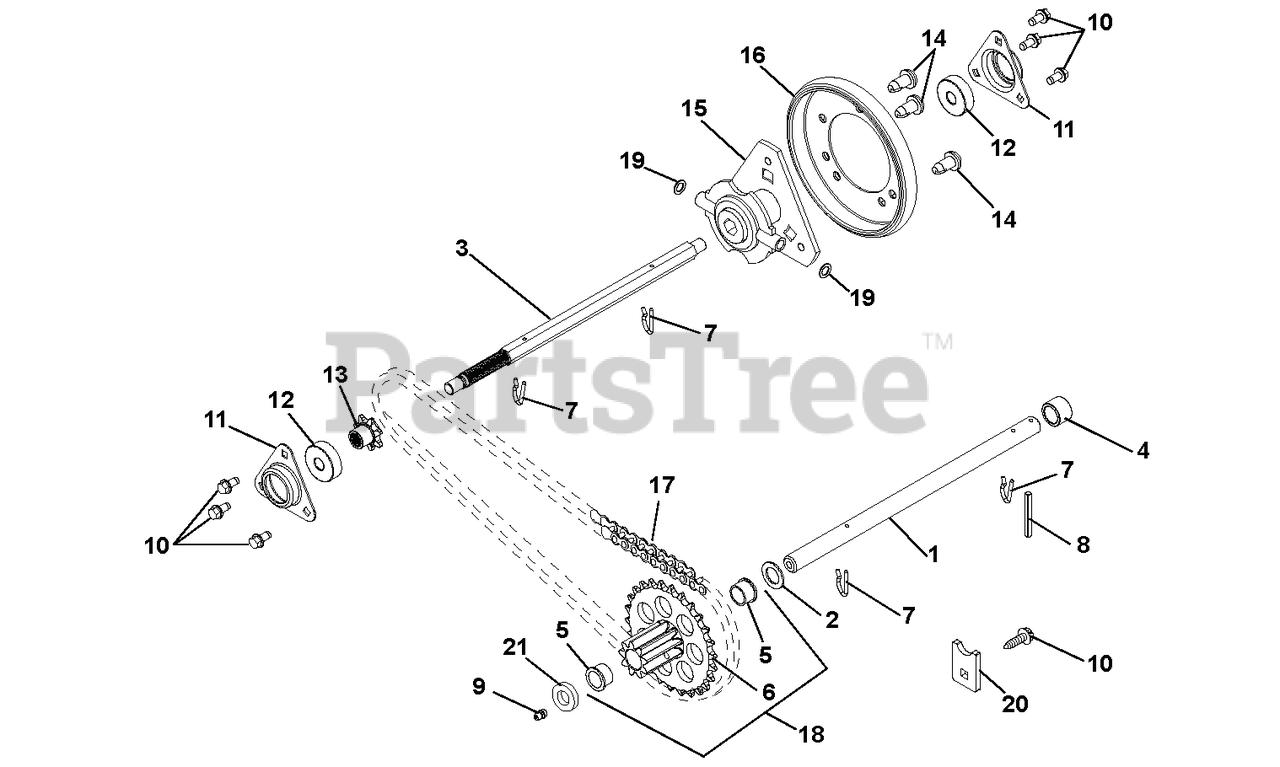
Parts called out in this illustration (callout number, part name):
1	SHAFT, PINION - HARDENED
2	WSHR-FL-STL .630X1.005X.062 YZ
3	SHAFT, HEX-W/SPLINE TRACK
4	SPACER, .635X.880X.611
5	BSHG-FLG .625X.750X.500X.875
6	PINION & SPROCKET
7	PIN, SPRING CLIP
8	@PIN-GRV .125X1.00 TP E ALLOY
9	ZERK,FITTING .25X.125 DRIVE IN
10	SCR-TAP .25-20X.50 HWH TR YWZ
11	FLANGE, BEARING
12	BRG-BALL .437X1.375X.437
13	SPROCKET, PINION 7T W/SPLINE
14	SCR-TAP SERRDHDTX .31-18X.50BP
15	CARRIER, DRIVE DISK
16	FRICTION, DISC
17	CHAIN - #41, 32 PITCHES
18	PINION & SPROCKET W/BUSHINGS
19	WSHR-FL-STL .505X1.00X.062YWZC
20	TAB, ANTI ROTATION
21	BSHG-SLV, .635X.880X.305
